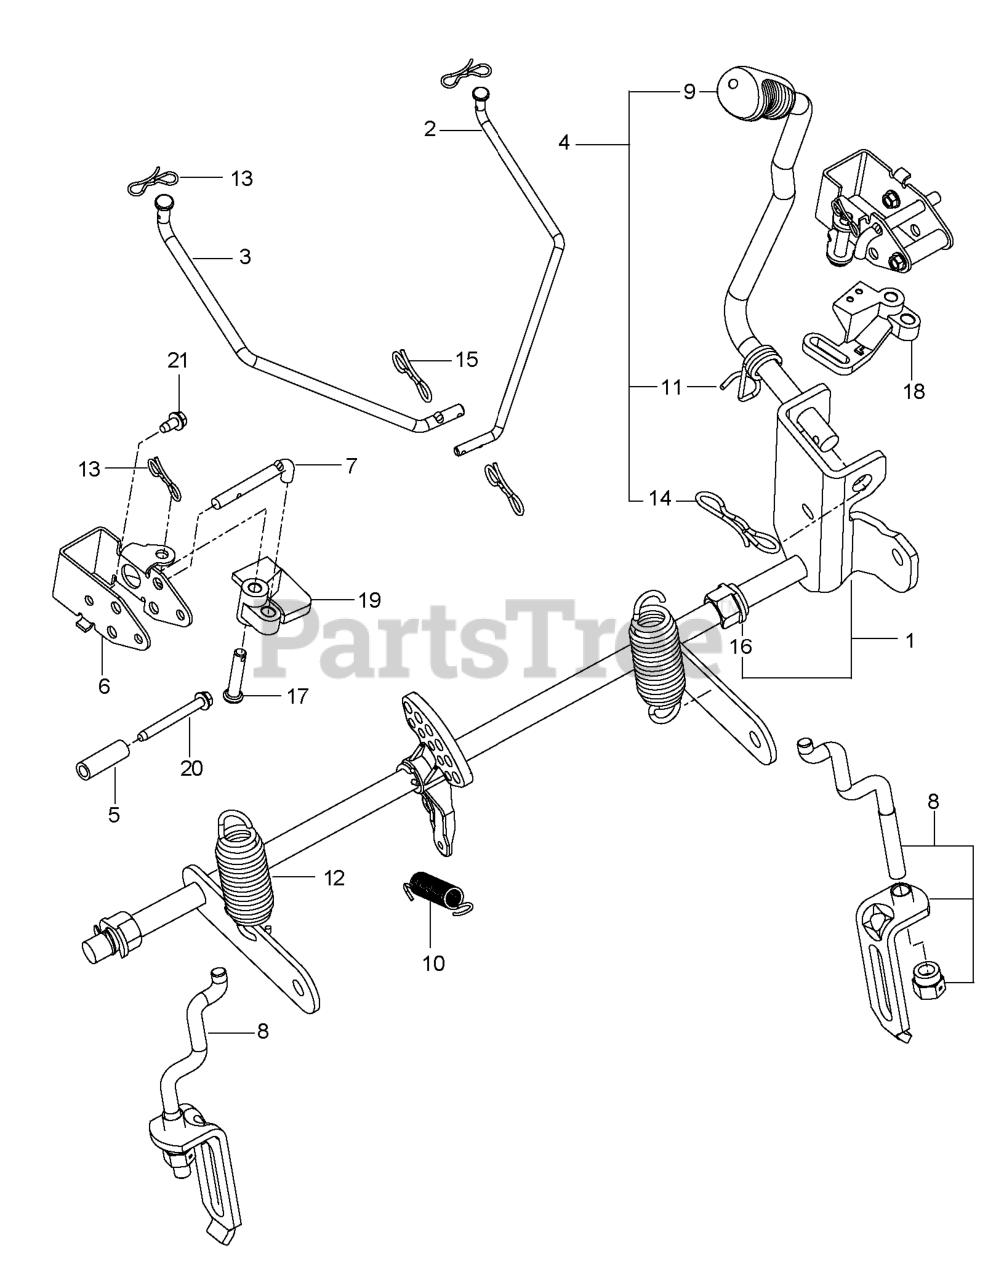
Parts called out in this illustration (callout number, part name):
1	SHAFT.ASM.RZ.DECK.LIFT.SRV
2	LINK.BRAKE.PARK.UPPER.LH
3	LINK.BRAKE.PARK.UPPER.RH
4	LIFT.LEVER.ASM.RZ.SERVICE
5	SPACER.334.ID.5.OD.1.5.L
6	BRACKET.BELLCRANK.PBRAKE X431
7	ROD.PUSH.BRAKE
8	LINK.ASM.RZ.LIFT.SERVICE
9	GRIP.HANDLE.LIFT.PVC.428
10	RETURN.BRAKE.PARK.AUTO
11	SPRING.TORSION.LIFT.HANDLE
13	PIN COTTER;LOCKING;BOWTIE;1IN
14	PIN.COTTER.7/16.BOW TI.
15	PIN.COTTER.5/16.BOW TI
16	PLASTIC NUT
17	PIN.5.16X1.5
18	BELLCRANK.LH
19	BELLCRANK.RH
20	SCREW THD;ROLL;1/4-20 X 2.25
21	SCREW.1/4-20X5/8
